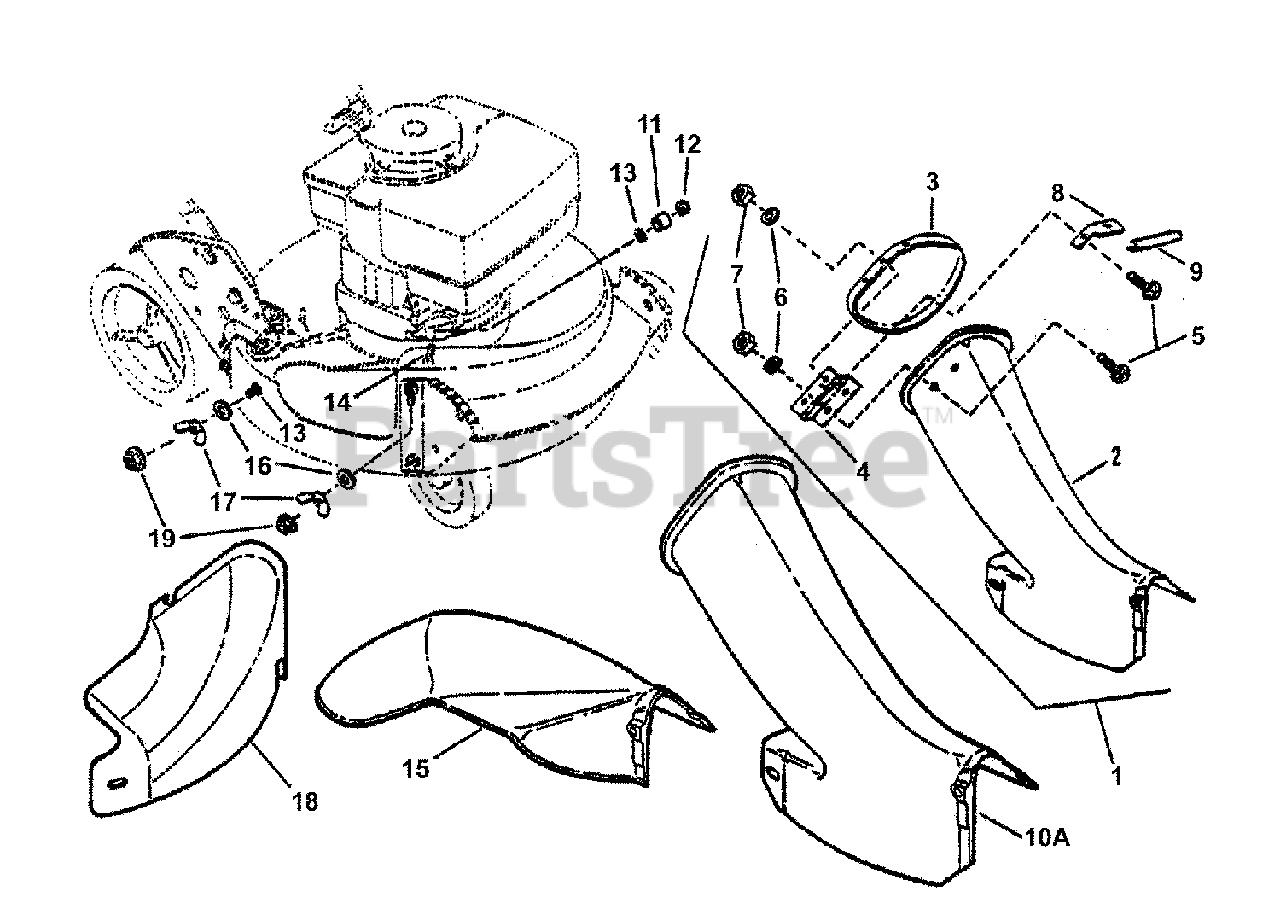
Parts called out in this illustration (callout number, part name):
1	ASSEMBLY, Bag Adapter & Cover
2	ADAPTER, Grass Bag
3	COVER, Bag Adapter
4	HINGE, Chute Cover
5	BOLT, 1/4-20 x 1/2" Short Neck Carriage GR5
6	WASHER, 1/4" Internal Tooth Lock
7	NUT, 1/4-20 Hex
8	STOP, Cover
9	MOLDING, Trim
10A	ADAPTER, Grass Bag
10B	ASSEMBLY, Grass Bag Adapter
11	SPACER, .316 I.D. x .375 O.D. x .310 thick
12	NUT, 5/16-18 Hex Large Flange Center Lock
13	RETAINER, 5/16" Bolt
14	BOLT, 5/16-18 x 3/4" Short Neck Carriage GR5
15	CHUTE, Side
16	WASHER, 3/8" Flat
17	WING-NUT, 5/16-18 Nyloc
18	COVER, 21" Deck
19	NUT, 5/16-18 Hex Large Flange Center Lock
